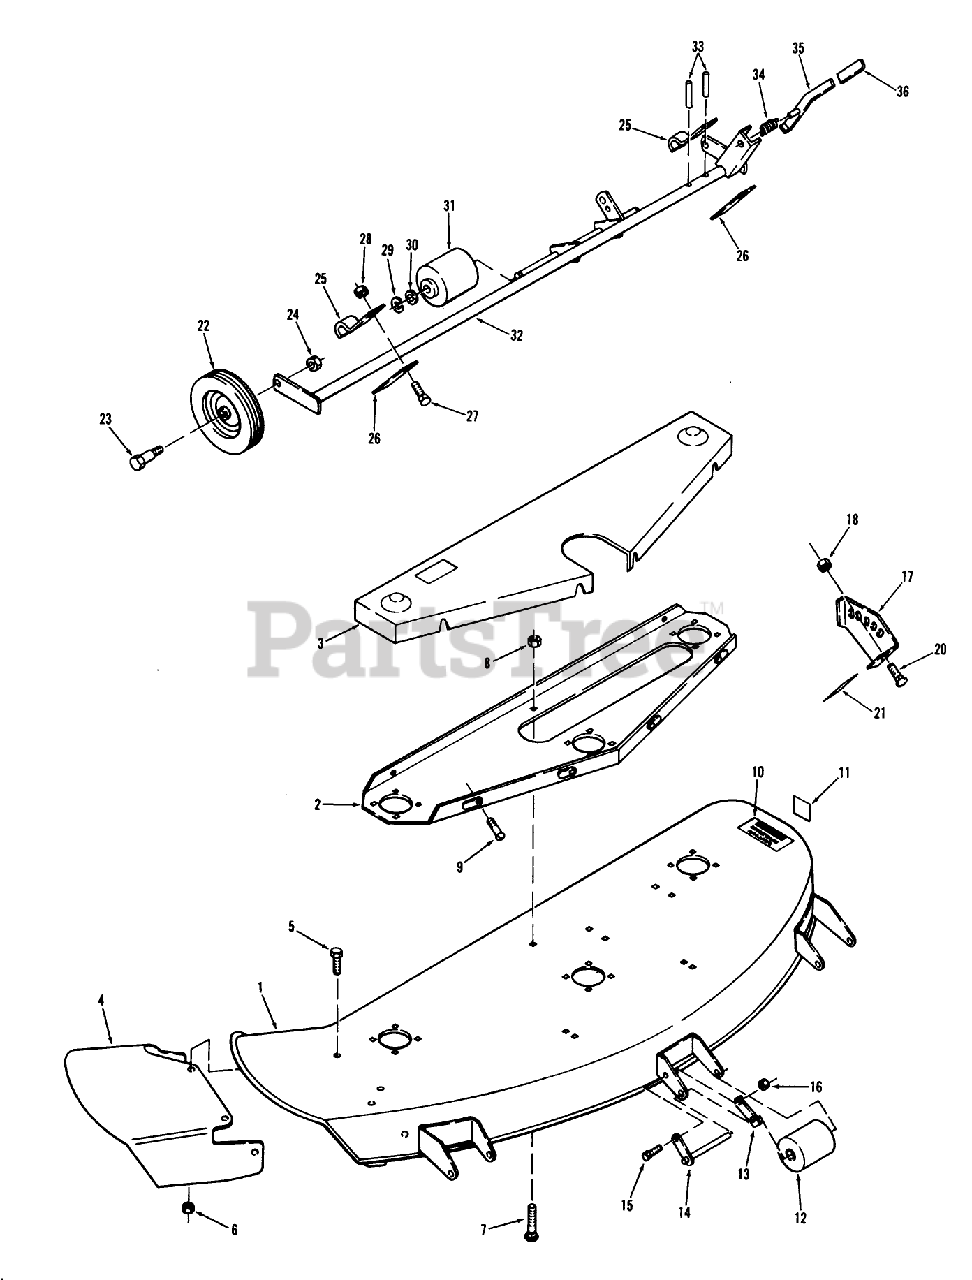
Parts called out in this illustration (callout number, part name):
1	Deck
1	Deck-42"
2	Bolt
3	Pulley-Right & Left
3	End Pulley
4	V-BELT
4	V BELT
5	WASHER
6	Bolt
7	Pulley-Center
7	Center Pulley
8	Nut
9	Idler Pulley
9	Pulley-Idler
10	Washer
12	SPRING R
13	WASHER 5/16 SAE
14	Nut
15	ASSY BAR IDLER SUPPO
16	Side Block
18	SLIDE
21	Nut
22	Bolt-Carriage
23	Bolt-Carriage
24	Cup-Spindle
25	SPIROL ROLL PIN
26	BLADE KIT 48 LF
26	BLADE KIT 42 LF
27	WASHER
28	Bolt
29	HOUSING SPINDLE
30	NEEDLE BEARING
31	SHAFT SPINDLE
32	Snap Ring
33	BEARING
34	INT SNAP RING
35	WASHER-THRUST
36	Spindle Assy.
